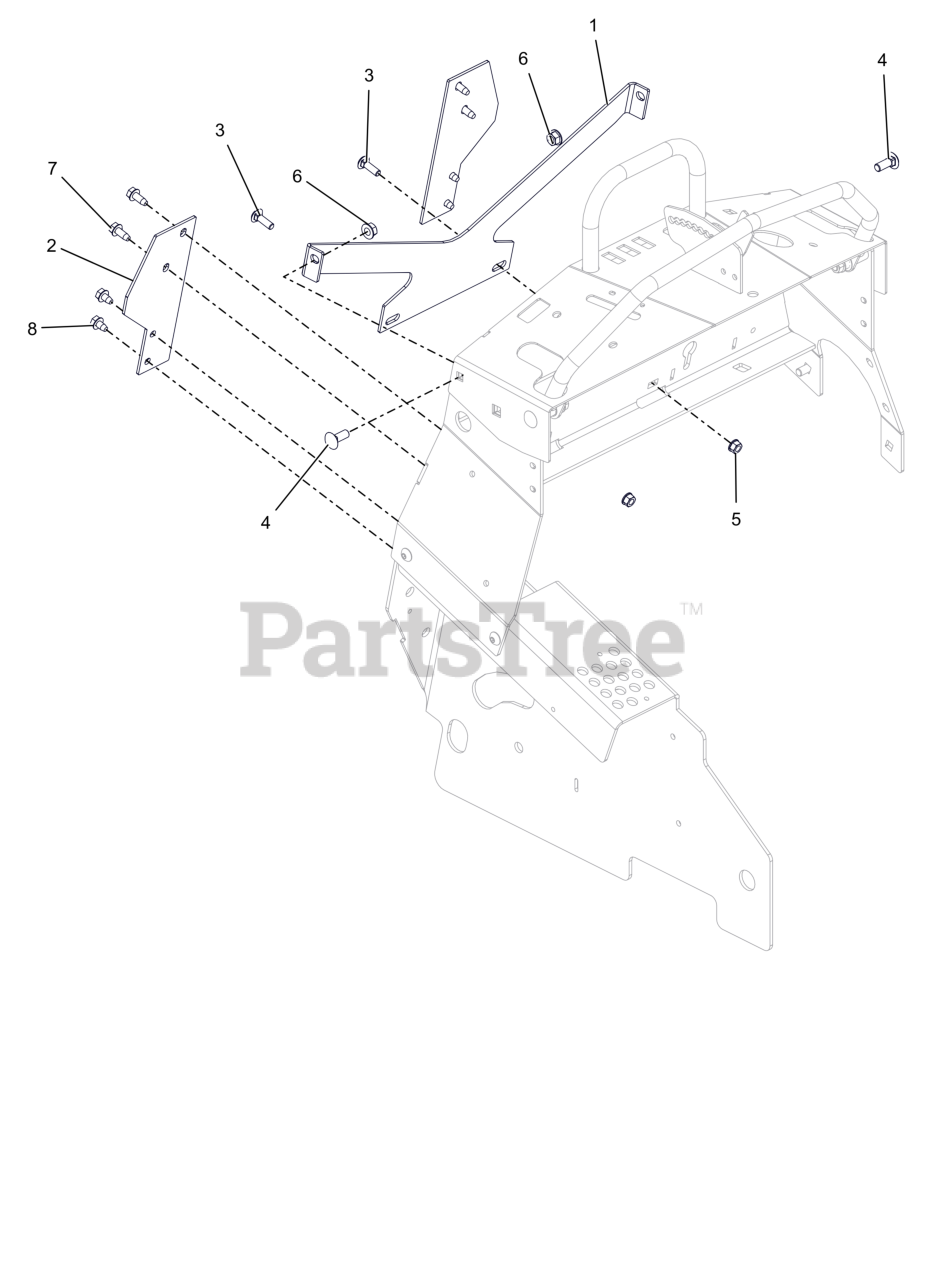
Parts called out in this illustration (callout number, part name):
1	BRKT, UPPER REAR SUPPORT (RED)
2	PLATE, LOWER REAR SUPPORT (RED)
3	BLT,RHSN .31-18X1.00 G5 ZCC
4	BLT, RHSN .38-16X1.00 G5 ZCC
5	NUT,LK-CTR-FLG .31-18 GF ZCC
6	NUT-LK-CTR-FLG .375-16 GF ZCC
7	SCR,TAP .312-18X.75 HWH TR ZCC
8	SCR,TAP .312-18X.50 HWH TR ZCC
